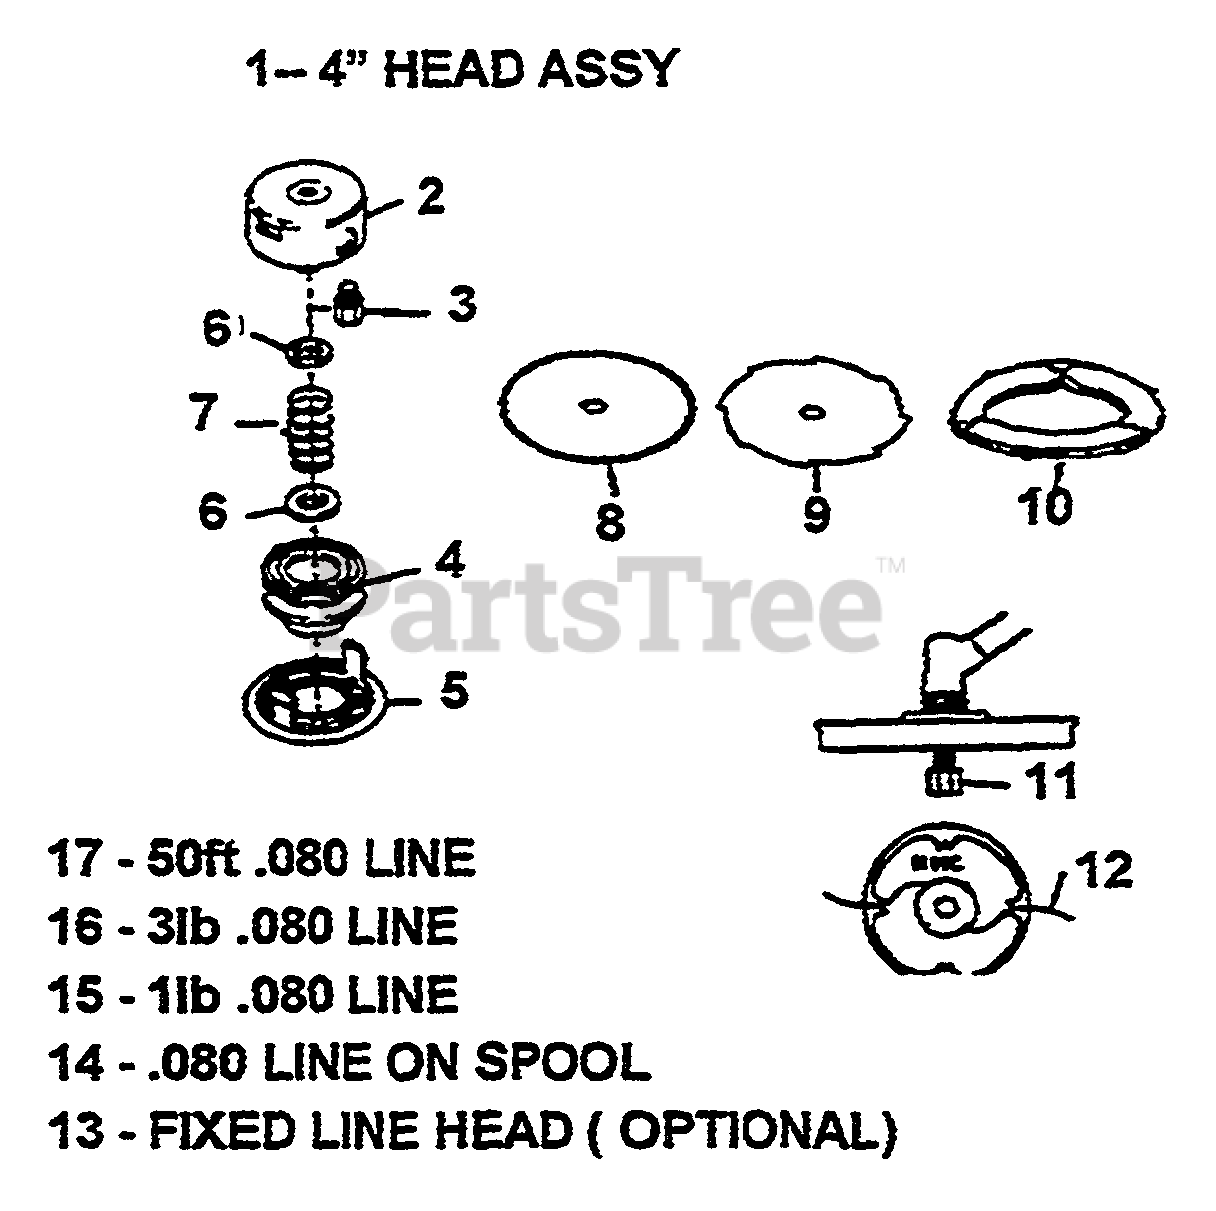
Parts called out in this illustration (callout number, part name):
1	4" HEAD ASSY
3	ARBOR BOLT
4	SPOOL
6	PLATE SPRING
7	SPRING
8	9" SAW BLADE
9	9" BRUSH BLADE
10	BLADE COVER
11	ARBOR BOLT
12	.105 LINE, 20" STRIPS
13	FIXED LINE HEAD
14	SPOOL 2 LINE
15	1 lb .080 LINE
16	3 lb .080 LINE
17	50 ft .080 LINE
